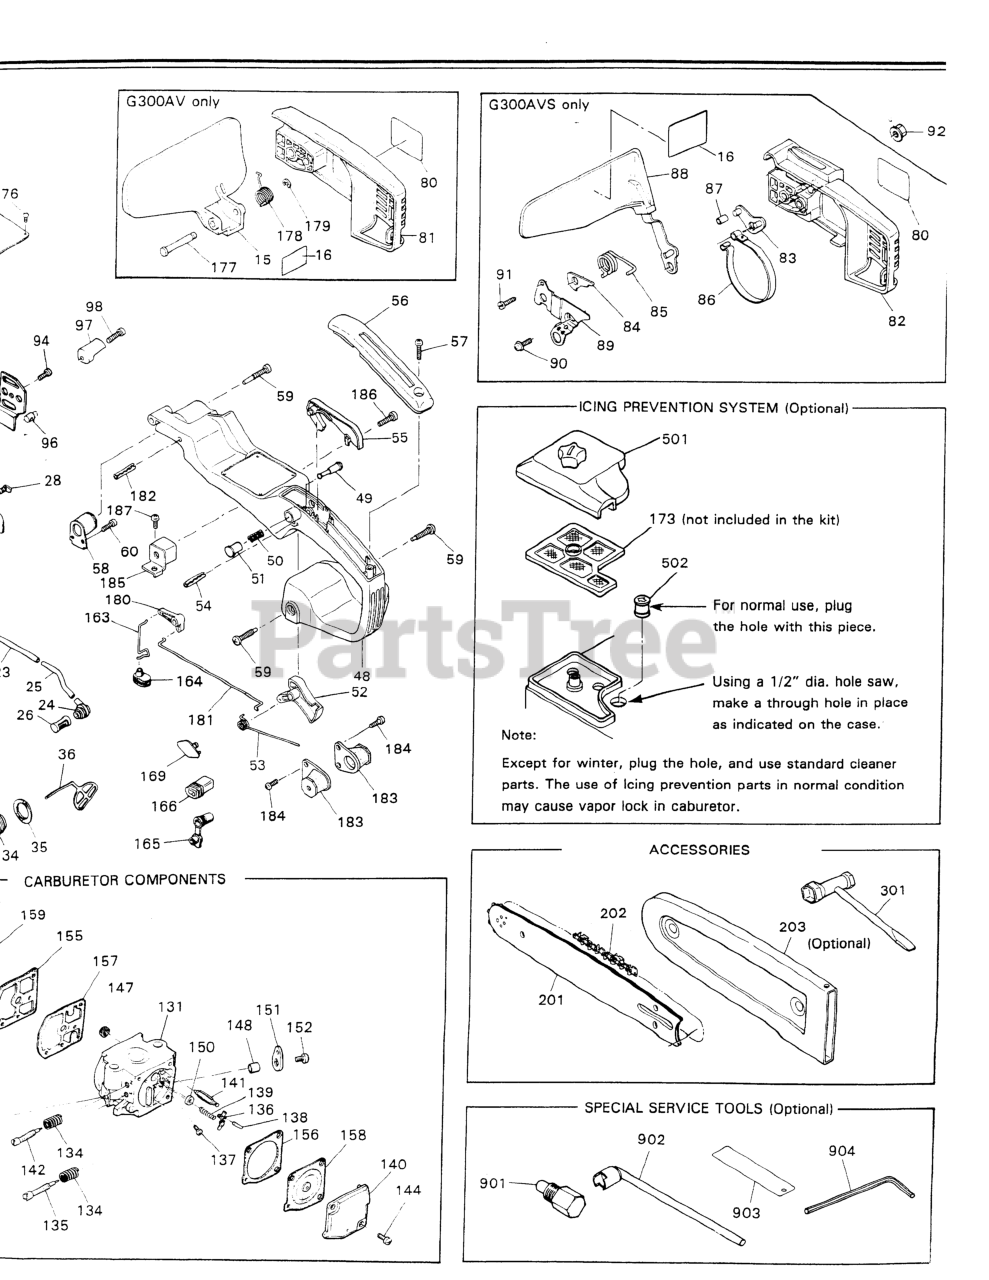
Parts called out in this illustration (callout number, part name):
23	PIPE (USE -85411)
24	GROMMET (RPLS -31320)
28	PIN
35	GASKET
48	HANDLE (NLA)
49	STOPPER
51	KNOB
53	SPRING
57	SCREW
60	SCREW (REPLACES 50030272)
82	CHAIN BRAKE ASSY
83	ARM ASSY
84	ARM (B) (RPLS -96221)
86	BAND
91	SCREW
92	NUT
94	SCREW
96	NUT
97	CATCHER, CHAIN (USE -53412)
134	SPRING (NLA)
137	SCREW (NLA)
141	VALVE (NLA)
144	SCREW (USE -81351)
147	STRAINER (NLA)
151	LEVER
155	KIT, GASKET
156	KIT, GASKET
157	KIT, DIAPHRAGM
158	KIT, DIAPHRAGM
159	KIT, DIAPHRAGM
164	GROMMET
165	GROMMET A
169	CAP
183	JOINT (C)
185	JOINT (D)
186	SCREW, M5 X 12
201	BAR 14
203	PROTECTOR (14.5
301	WRENCH, PLUG
902	WRENCH (TOOL)
903	GAUGE (TOOL)
904	WRENCH (TOOL)
NI	MUFFLER ASSEMBLY
NI	PIPE COMP (USE -31202)
NI	PIPE ASSEMBLY
NI	HANDLE (F)
NI	CLUTCH ASSEMBLY
NI	CHAIN BRAKE ASSY
NI	KIT, DIAPHRAGM
NI	LABEL, WARNING
NI	ICING KIT
